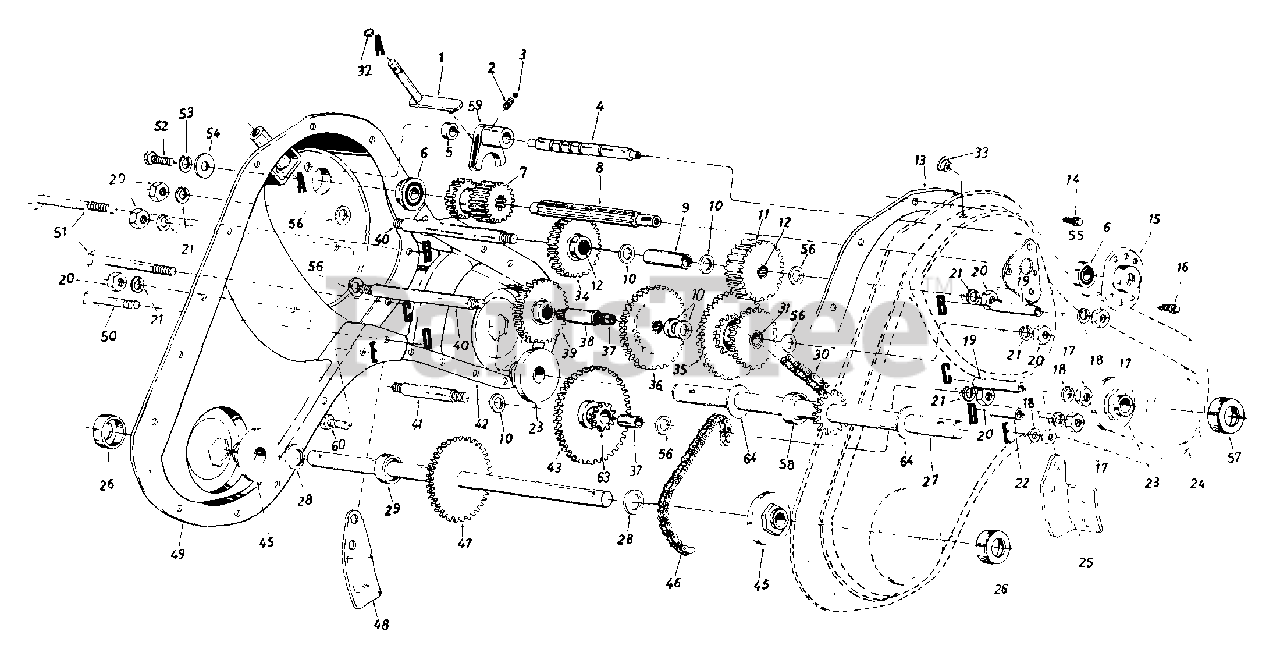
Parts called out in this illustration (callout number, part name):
1	Shifting Bracket Ass'y.
2	Compression Spring .50" Lg.
3	Ball Detent .250" Dia.
4	Detent Shaft 1/2" Dia.
5	Spacer .505" I.D. x .88" O.D.
6	Ball Brg. .62" I.D. x 1.38"
7	Spur Gear 16T (Input)
8	Input Spline Shaft 7/8"
9	Spacer .657" I.D. x 2.85" Lg.
10	Fl-Wash. .640" I.D. x 1.24"
11	Spur Gear 30T 7/8" I.D.
12	Needle Bearing 5/8" I.D.
13	Gasket - Trans. Hsg.
14	Hex S-Tap Scr. 1/4-20 x .5"
15	1-3/8" Dia. Bearing Housing
16	Hex TT-Tap Scr. 1/4-20 x .75"
17	Hex Nut 5/16-18 Thd.
18	L-Wash. 5/16" I.D.
19	Spacer 1.56" Lg.
20	Hex Nut 7/16-20 Thd.
21	Bell-Wash. .45" I.D. x 1.0"
22	Spacer 1.015" Lg.
23	Tine Shaft Brg. 1.002 x 2.50
24	Trans. Housing Ass'y. - L.H.
27	Tine Shaft Ass'y. 1" O.D.
28	Fl-Wash..76" I.D. x 1.5" O.D.
29	Spacer .75" I.D. x .50" Lg.
30	Chain #50 5/8 Pitch x 52 Links - Endless
31	Needle Bearing 5/8" I.D.
32	Snap Ring
33	Taper Cap Plug
34	Spur Gear 30T 12/16" I.D.
35	30/44T Gear Ass'y. Comp.
36	Spur Gear 44T
37	Sleeve Bearing
38	Gear Hub 3/4" I.D. x 3" Lg.
39	Spur Gear 30T 1.0" I.D. x 1/2" W
40	Jack Shaft 5/8" Dia. x 5"
41	Jack Shaft 5/8" Dia. x 2.38"
42	Trans. Housing Ass'y - R.H.
43	Spur Gear 55T
45	Wheel Brg .752" x 2.5"
46	#420 Chain 1/2 Pitch x 50 Links - Endless
47	Wheel Shaft Ass'y. 15.6"
51	Hex Bolt 5/16-18 x 2.5"
52	Hex Bolt 1/4-20 x .62" Lg
53	L-Wash. 3/8" I.D.
54	Fl-Wash. 1/4" I.D. x .93" O.D.
55	Gear Positioner Bracket
56	Fl-Wash. 7/16" I.D. x 1-3/8"
57	Dust Cover Ass'y 1" Shaft
58	Spacer 1" I.D. x 2" O.D.
59	Shifting Fork
60	Hex Bolt 5/16-18 x .75" Lg
63	10T Sprocket Ass'y.
64	Thrust Wash 1.03" I.D. x 1.62" O.D.
